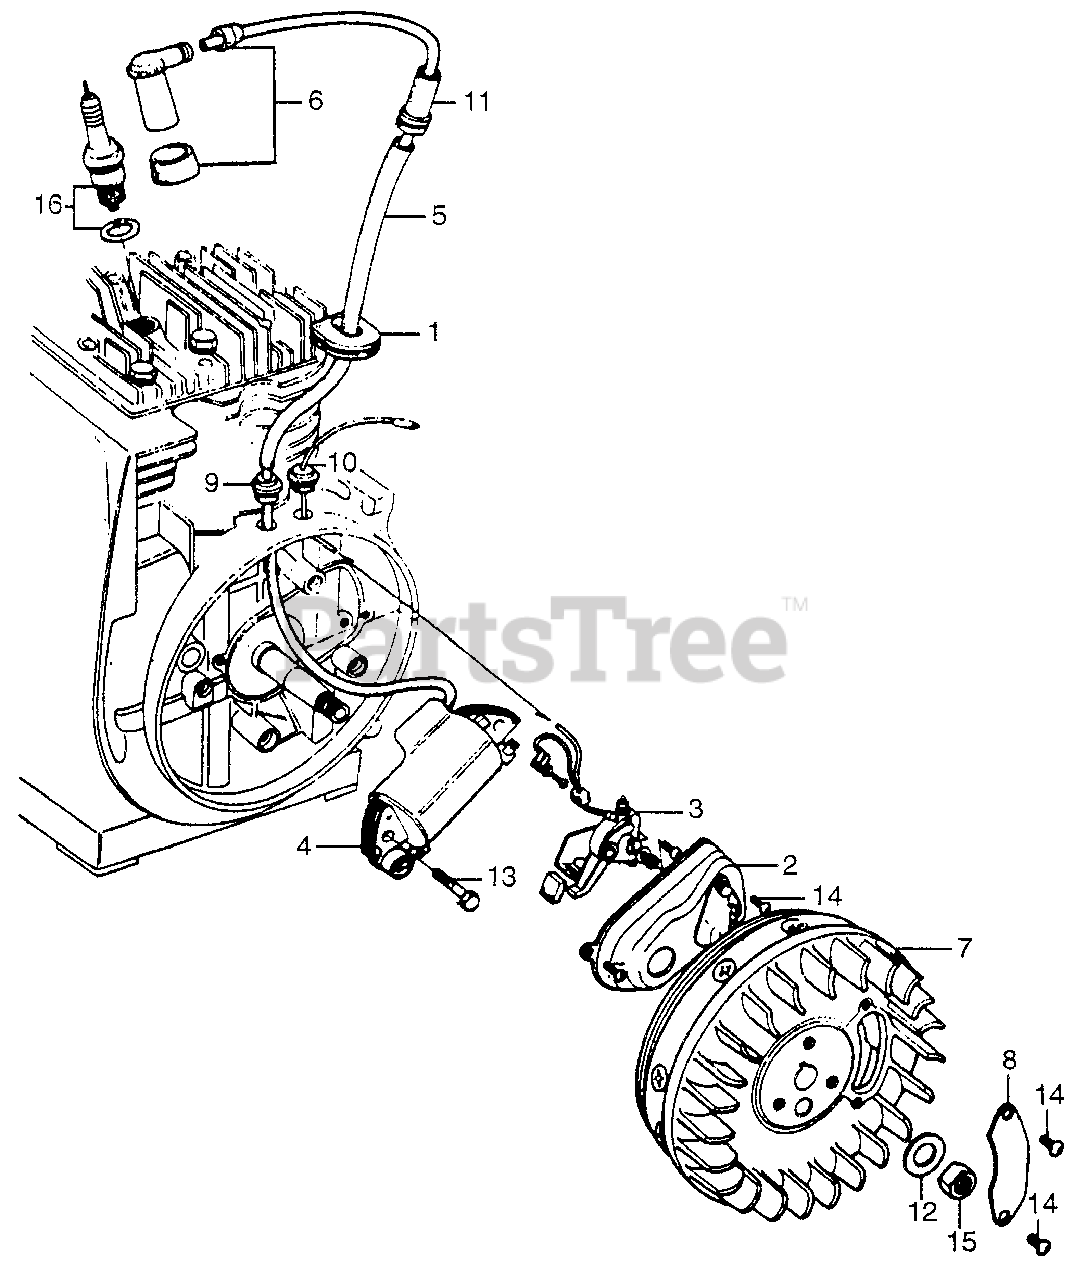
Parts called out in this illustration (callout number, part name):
1	GROMMET, WIRE
2	COVER, POINTS
4	COIL, IGNITION
5	TUBE, IGNITION RUBBER
6	CAP ASSY., NOISE SUPPRESSOR
7	FLYWHEEL (NOT AVAILABLE)
8	COVER, FLYWHEEL WINDOW (NOT AVAILABLE)
9	GROMMET, WIRE
10	GROMMET, WIRE
11	GROMMET, IGNITION WIRE
12	WASHER (12MM)
13	BOLT, HEX. (6X28)
14	SCREW, PAN (5X10)
15	NUT, HEX. (14MM)
16	SPARK PLUG (B6HS) (NGK)
